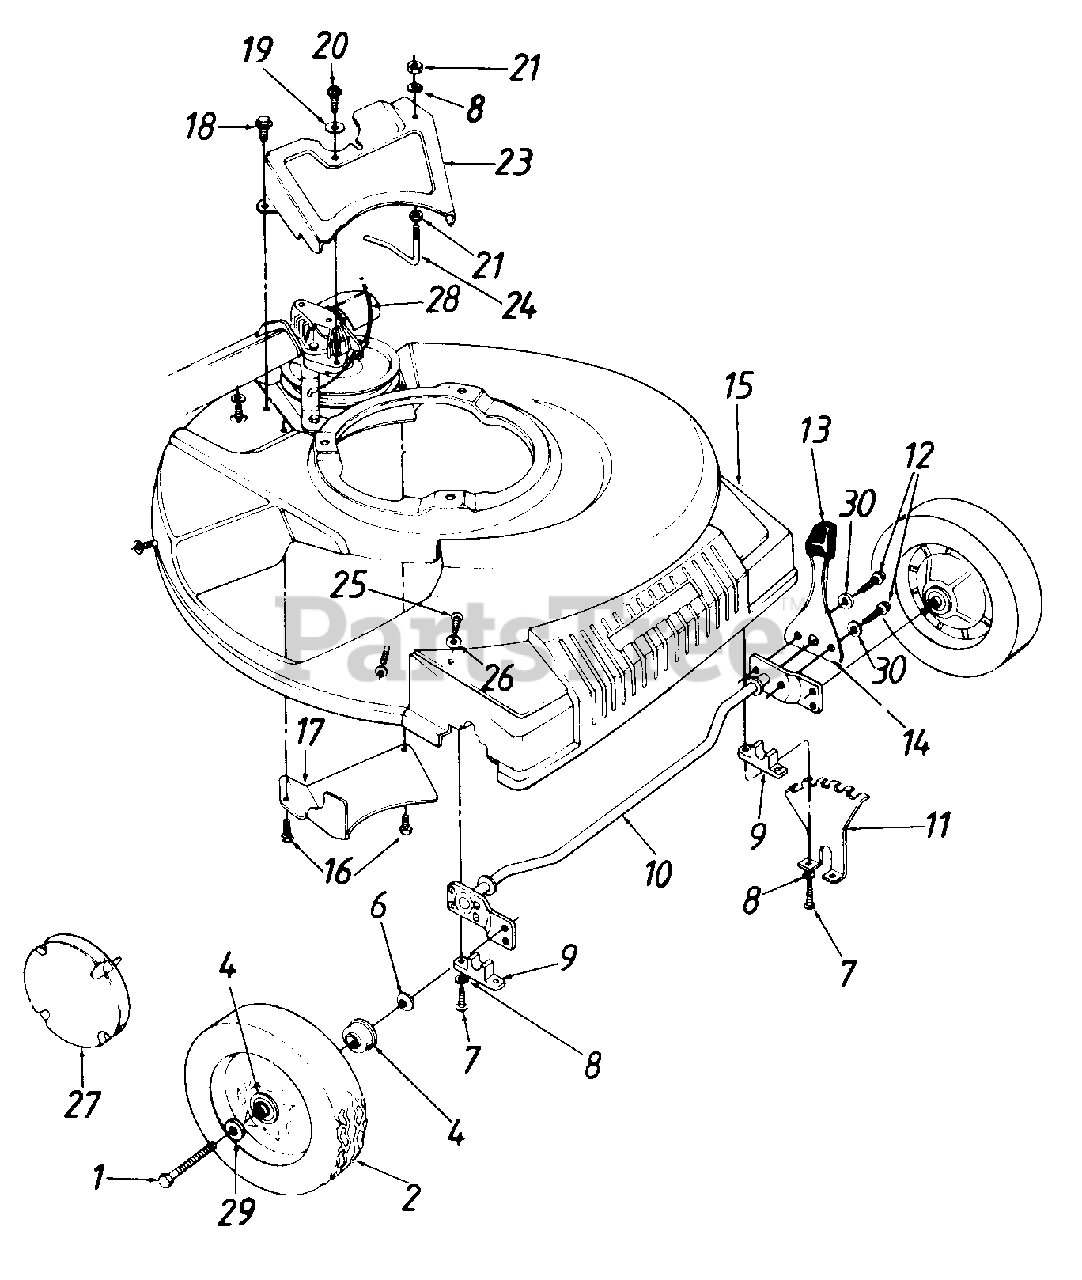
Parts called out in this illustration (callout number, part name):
1	Front Axle Bolt
2	Wheel Ass'y. Comp. 8 x 2"
4	Flange Ball Brg. .501" I.D.
6	Bell-Wash. .380" I.D. x .88
7	Hex Wash. Hd. B-Tap Scr. 1/4-20
8	L-Wash. 1/4" I.D.
9	Block Bushing
12	Hex Wash. Hd. TT-Tap Scr. 1/4-20 x .38" Lg.
13	Knob
14	Spring Lever
15	Plastic Front End
16	Hex B-Tap Scr. 1/4" x .38"
19	Bell-Wash. .265" I.D. x .75
20	Hex Wash. Hd. B-Tap Scr. 1/4 x .62"
21	Hex Nut 1/4-20 Thd."
25	Truss B-Tap Scr. 5/16 x .75"
26	Bell-Wash. 345" I.D. x .88" O.D.
27	Hub Cap
28	S.P. Cable 50" Lg.
29	Wave Wash. 53" I.D. x 78" O.D.
30	External L-Wash. 1/4" I.D.
